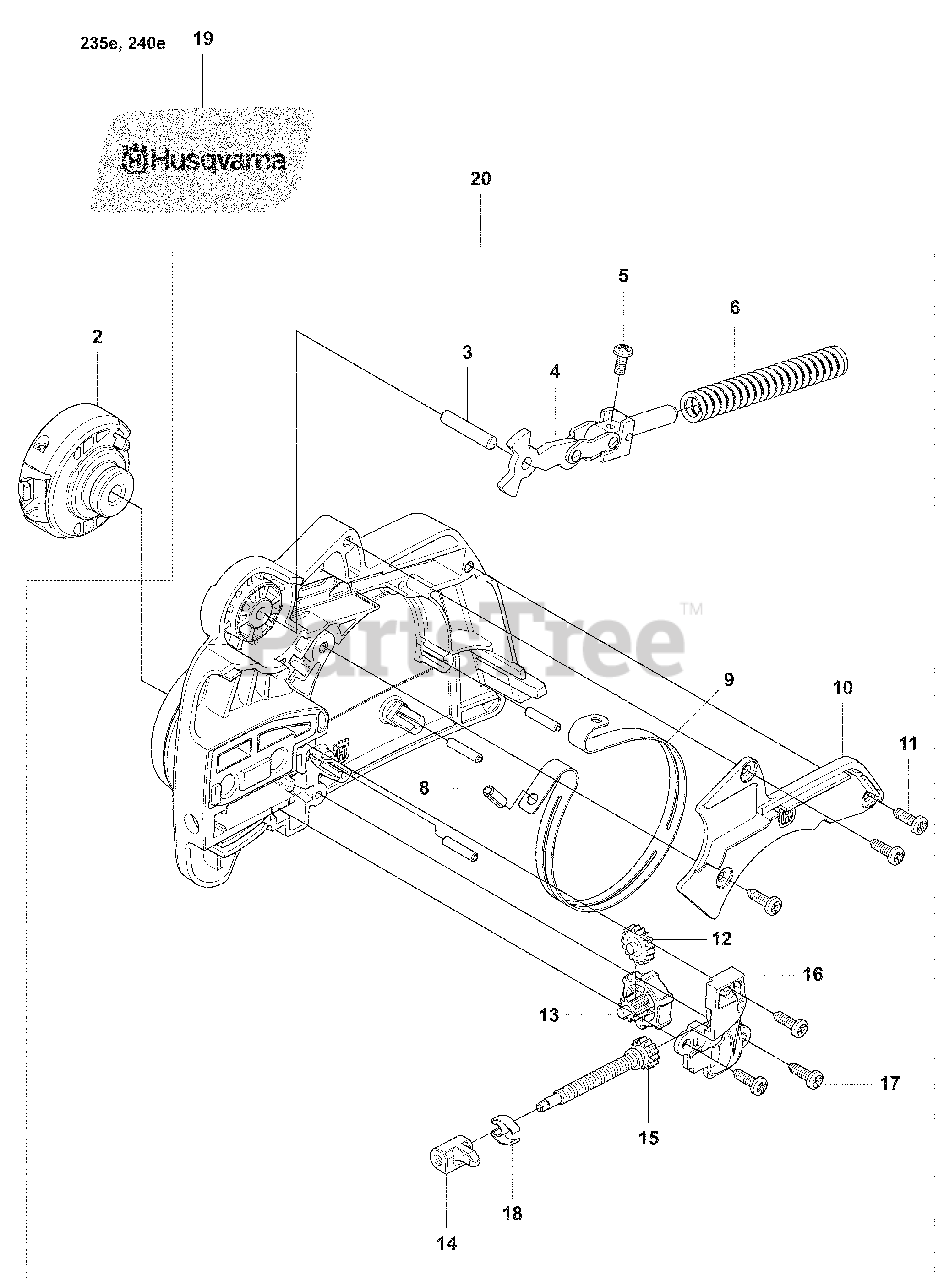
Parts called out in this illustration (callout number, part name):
2	ASSEMBLY KNOB EZT
3	PIN, DOWEL
4	ASSY, FRONT LINK
5	M3.83 X 1.81 X 9 PLASTITE
6	SPRING COMPRESSION
8	PIN, BAND RETAINER
9	BRAKE BAND
10	COVER, BRAKE BAND
11	SCP#6-19 X .437 .PL. PAN.
12	GEAR, IDLER
13	WHEEL, GEAR ADJUSTER
14	PIN, BAR ADJUSTING
15	ASSY ADJUSTER SCREW
16	COVER, GEAR
17	SCP#6-19 X .437 .PL. PAN.
18	Clip, EZT Spring
19	Decal, EZT Clutch Cover
20	Chain brake assembly
